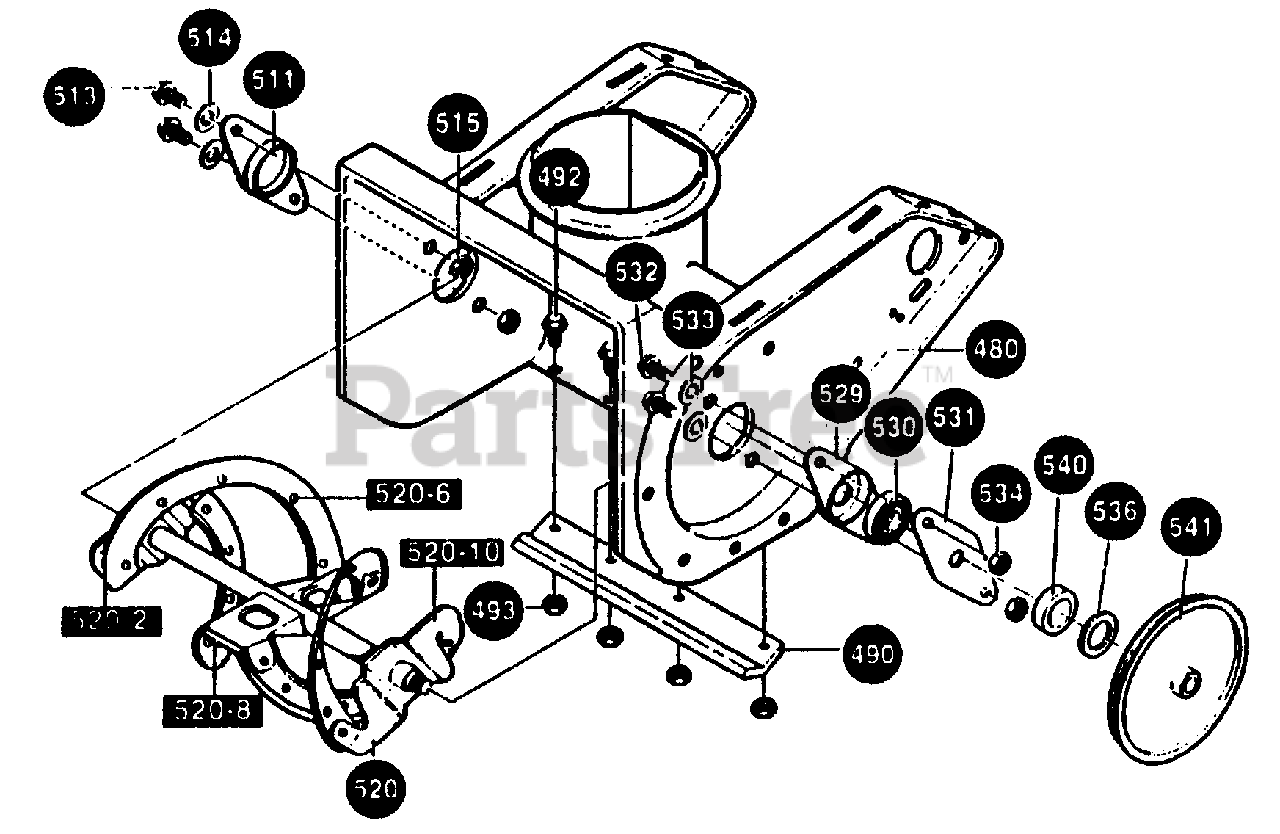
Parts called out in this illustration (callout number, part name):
480	HSNG, ASSY
490	BLADE, SCRAP
492	SCREW, 1/4-20X .63
493	NUT, 1/4-20 WDFL MAC-LOCK
511	BEARING, FLANGE
513	SCREW, 1/4-20X .88
514	WASHER, FLAT .281X .63X.065
515	NUT, 1/4-20 WDFL MAC-LOCK
520	AUGER, ASSY
520-2	BLADE, AUGER
520-6	RIVET, OVSET
520-8	BLADE CENTER
520-10	AUGER & BLADE ASSY
529	RETAINER, BEARING
530	BRNG, BALL
531	PLATE,RETAINING BEARING
532	SCREW, 1/4-20X .62
533	WASHER, FLAT .281X .63X.065
534	NUT, 1/4-20 REGHEXCTRLK
536	WASHER, FLAT .640X1.25X.06
540	SPACER, SLEV .640X .88X .15
541	PULLEY, POLYV 6"OD
